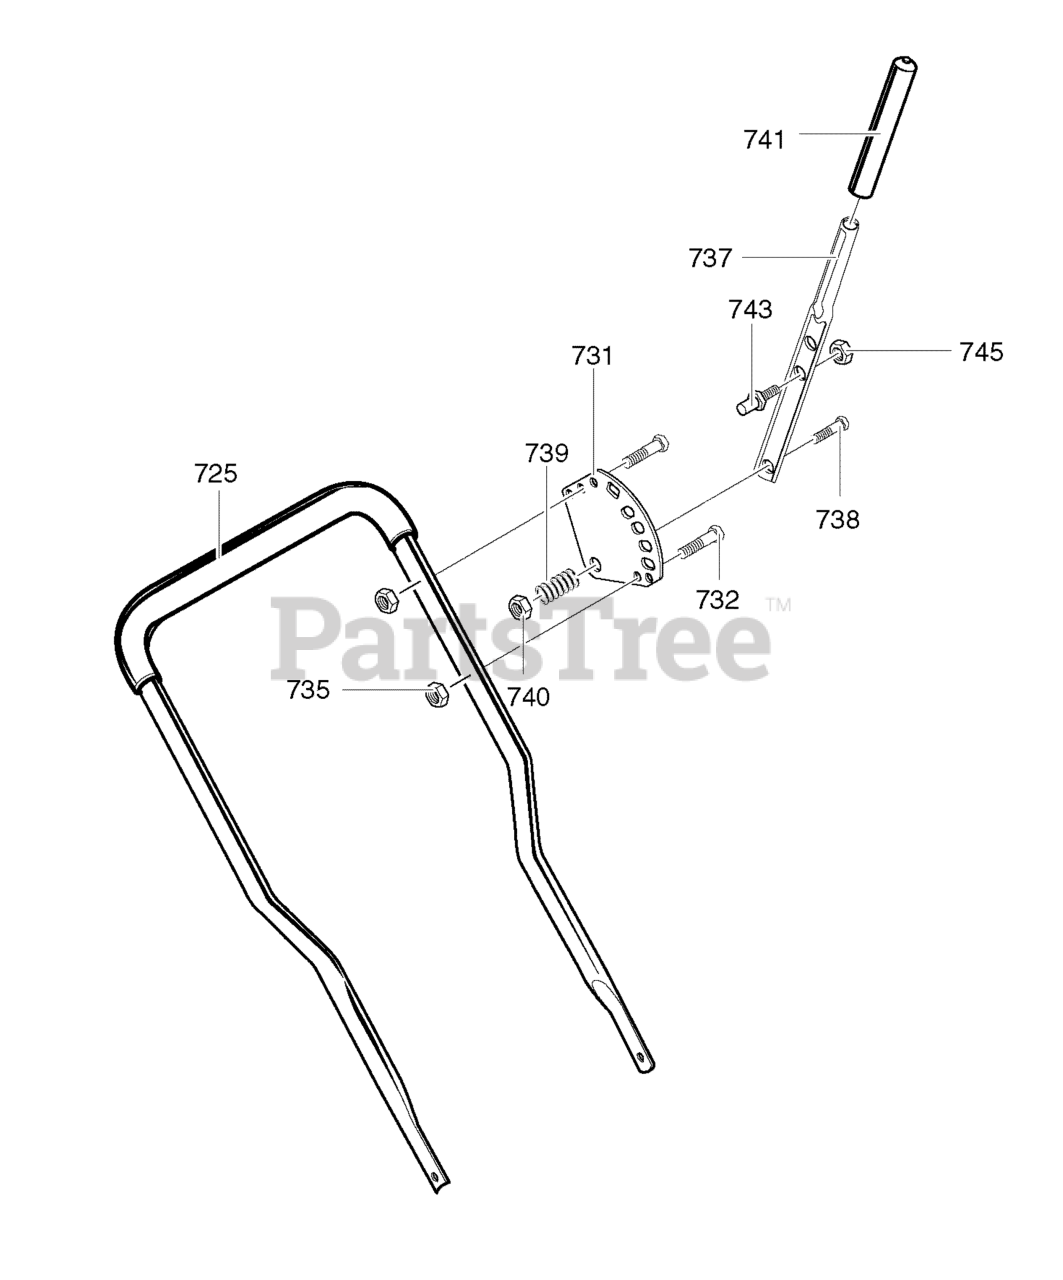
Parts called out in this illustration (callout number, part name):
725	UPPER HANDLE & FOAM
731	PLATE, Selector
732	SCREW, 1/4-20x1.25
735	NUT, 1/4-20
737	HANDLE, Depth Adjust
738	SCREW, 5/16-18 x 1.25
739	SPRING, Compression
740	NUT, 5/16-18
741	GRIP, Hand
745	NUT, 3/8-16
